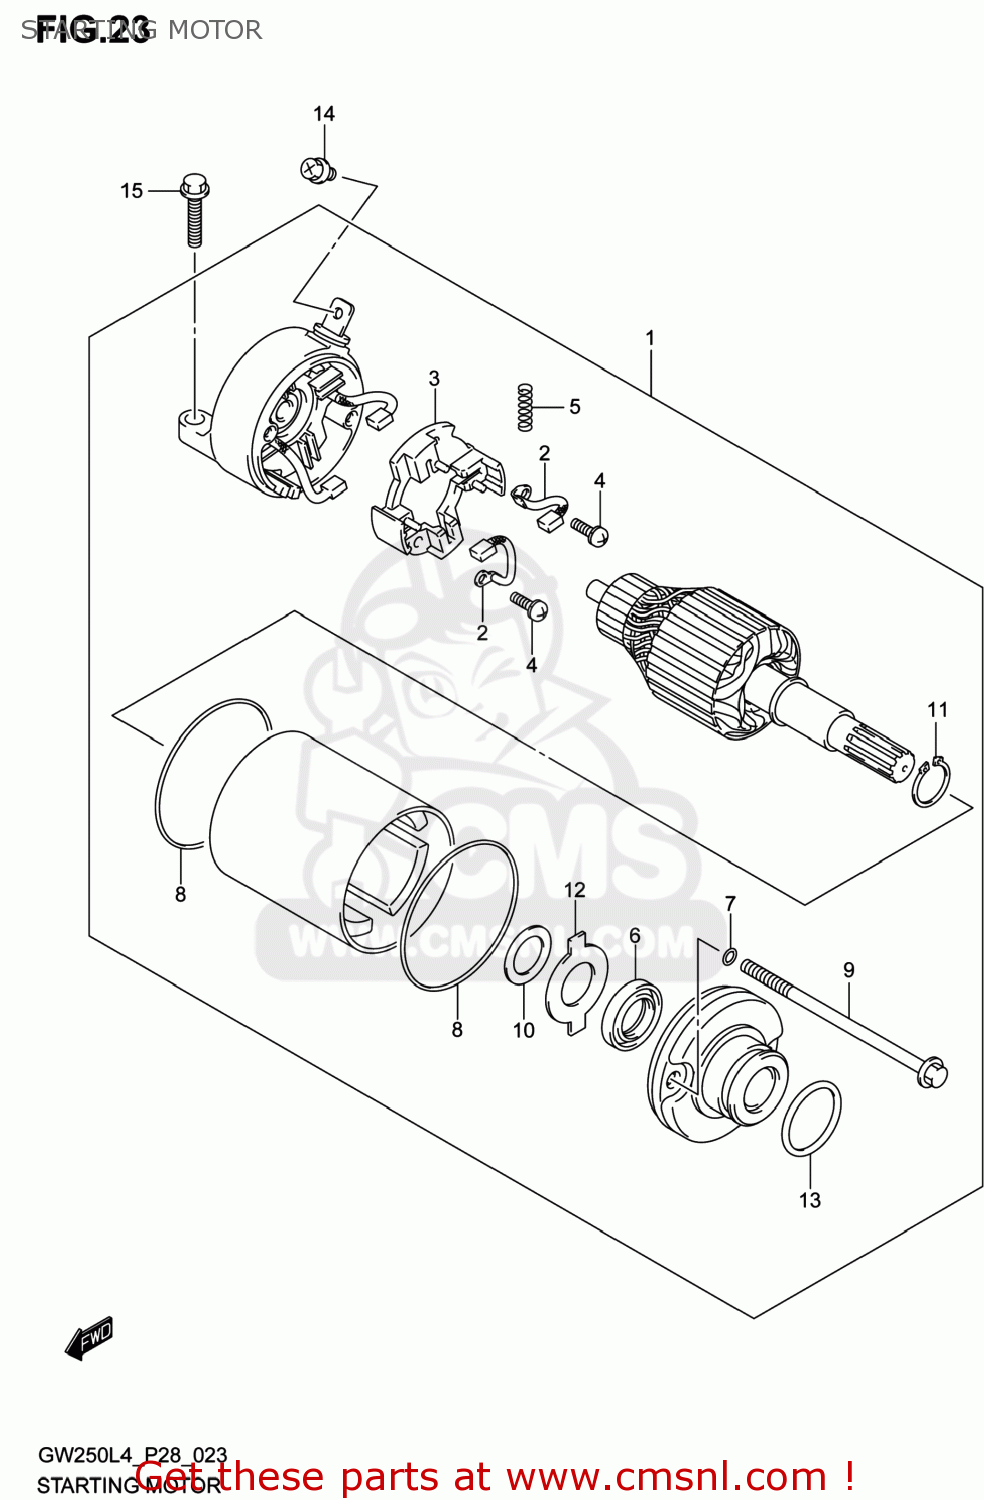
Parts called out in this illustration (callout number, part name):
1	MOTOR ASSY,STARTING
2	BRUSH
3	BRUSH HOLDER
4	SCREW
5	SPRING
6	SEAL,OIL
7	O RING
8	O RING
9	BOLT
10	SHIM
11	RING,SNAP
12	PLATE LOCK
13	O RING(D:3,ID:24.5)
14	SCREW(5X8)
15	BOLT
